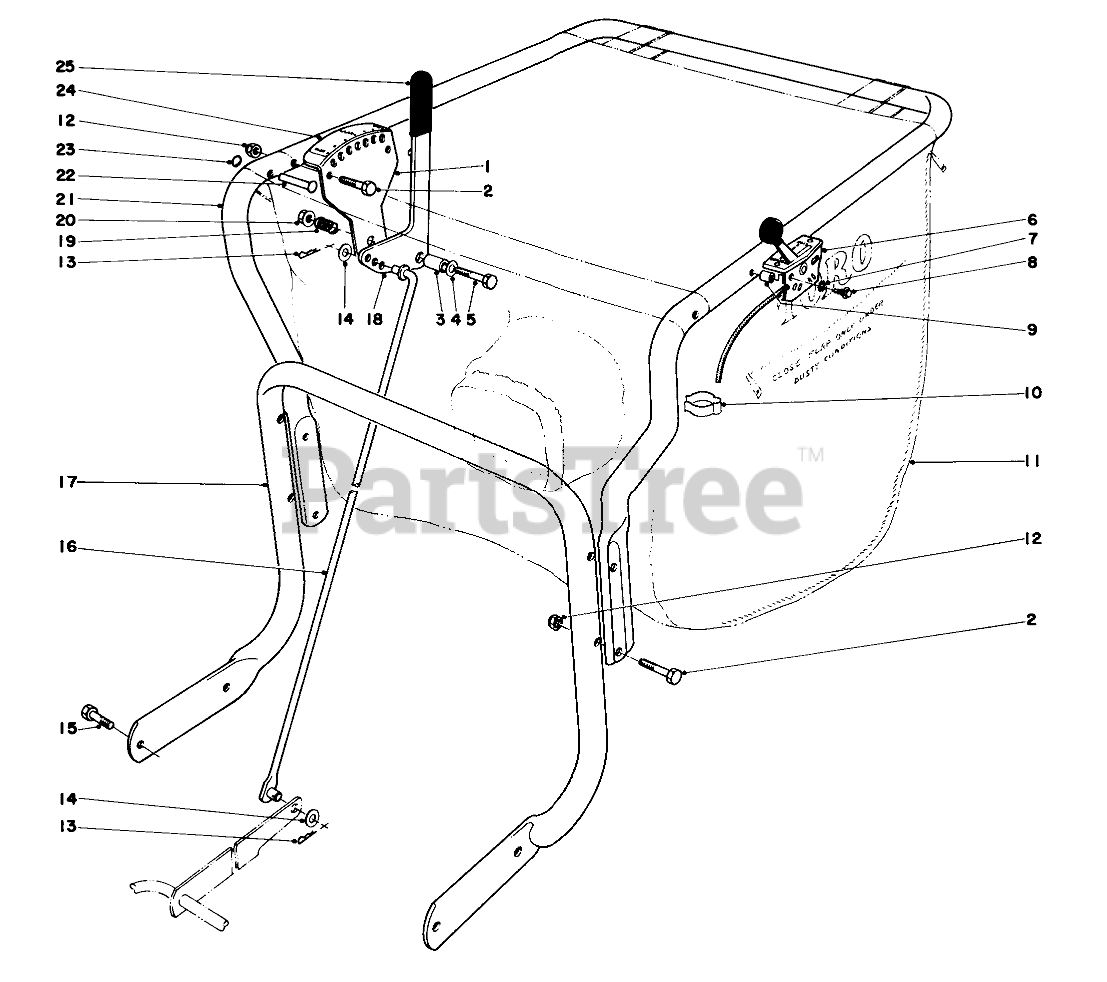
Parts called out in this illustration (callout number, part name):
1	Adjustment Bracket
2	SCREW-HH
3	SPACER
4	WASHER-FLAT
5	SCREW-HH
6	THROTTLE CONTROL
7	WASHER-LOCK, EXT
8	10-24 X 1 PAN HD SCR
9	SPACER
10	BODEN CLIP
11	Bag-Vacuum
12	NUT-LOCK, CONE
13	PIN-COTTER
14	WASHER-FLAT
15	SCREW-HH
16	Connector Rod
17	HANDLE
18	Handle-Adjustment
19	SPRING-COMPRESSION
20	NUT-HF
21	HANDLE-UPPER, VACUUM
22	RIVET
23	RING-GRIP
24	HT ADJ DECAL
25	GRIP-HANDLE
